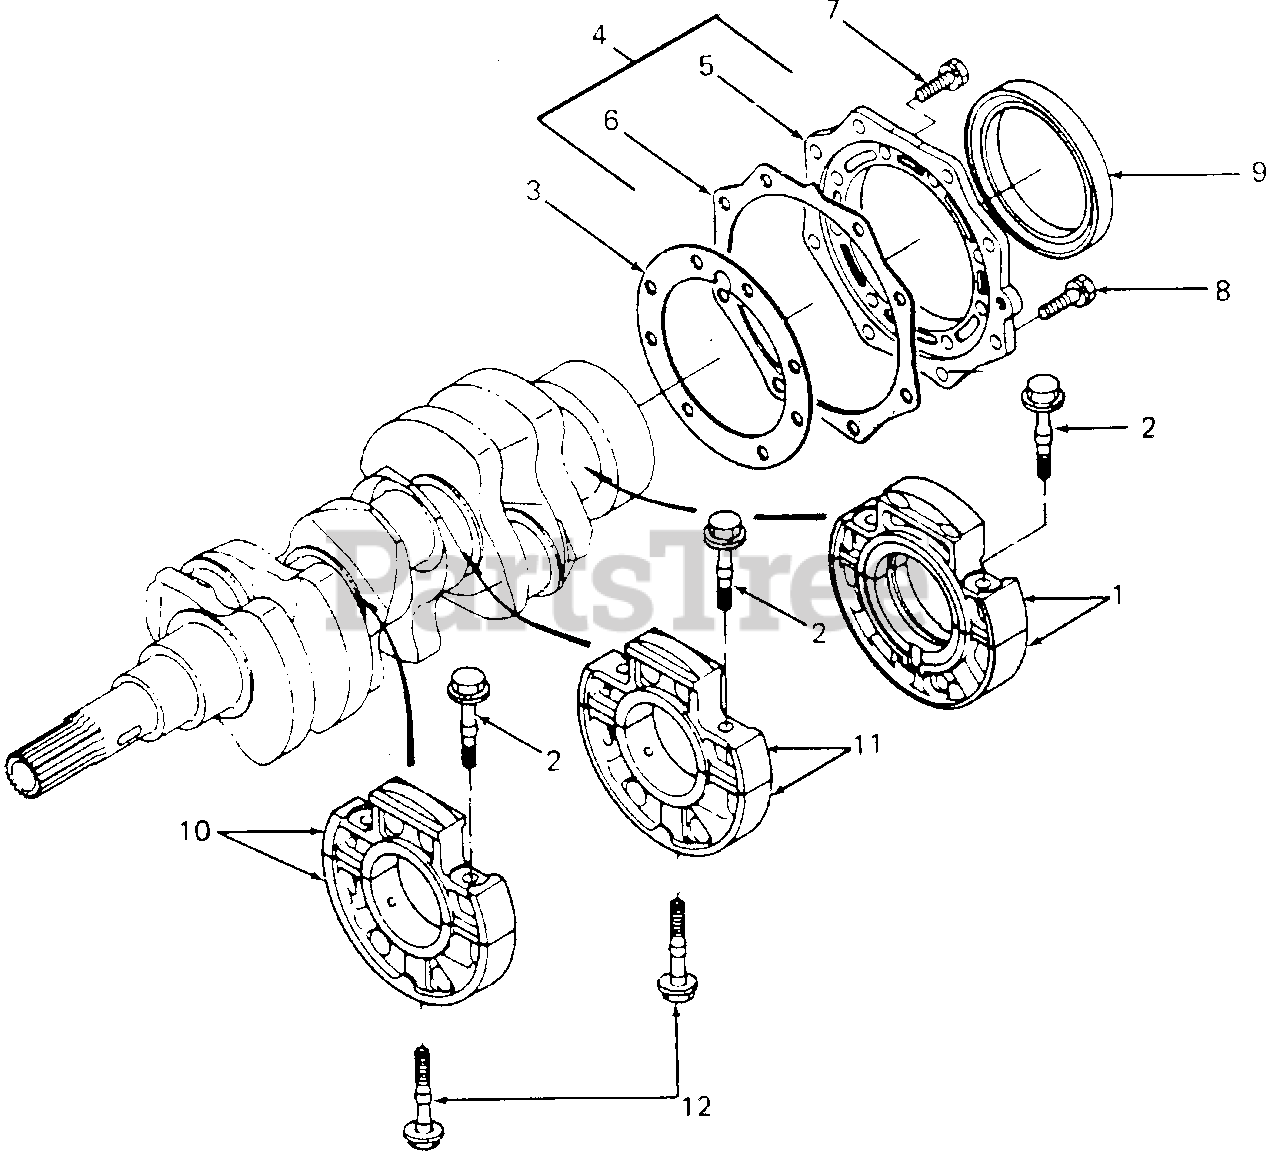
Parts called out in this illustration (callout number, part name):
1	Case, Main Bearing
2	Bolt, Bearing Case
3	Shim, Bearing Case
4	Cover Assy, Bearing Case
5	Cover, Bearing Case
6	Gasket, Bearing Case
7	Screw, Hex Cap w/Washer
8	Screw, Hex Cap
10	Case, Main Bearing
11	Case, Main Bearing
12	Bolt, Bearing Case
